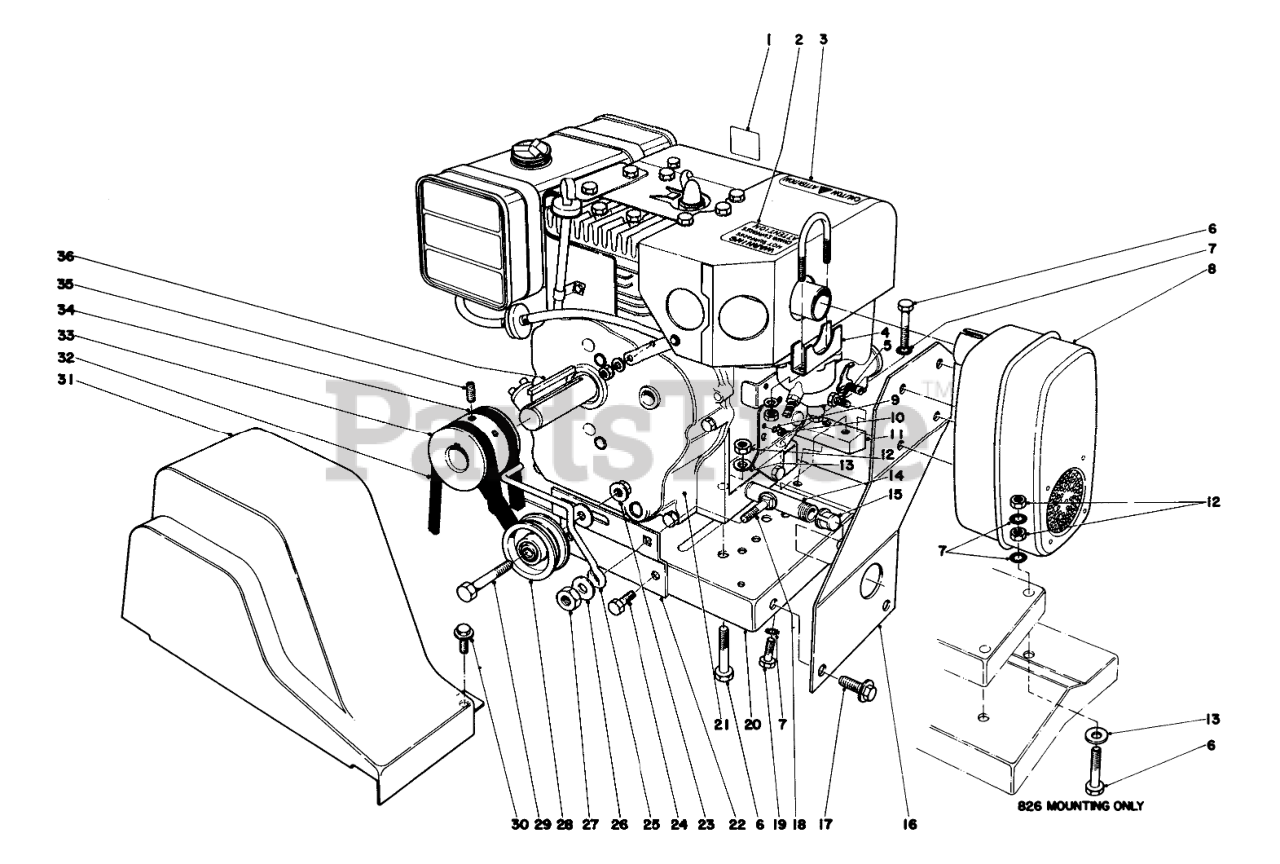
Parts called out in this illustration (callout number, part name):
1	CHOKE DECAL
2	Decal Hot Surface Warning
3	CAUTION DECAL
4	MUFFLER CLAMP
5	1/4-20 X 1/2 SEMS MS
6	SCREW-HH
7	WASHER-LOCK, INTERNAL
8	Muffler
9	WASHER-LOCK/INT
10	NUT-LOCK
11	Block Engine Mounting
12	NUT-LOCK, NI
13	WASHER-PLAIN
14	NIPPLE-PIPE
15	CAP-PIPE
16	Muffler Mounting Bracket
17	SCREW-HHF
18	SCREW-CARR
19	SCREW-HH
20	Base-Engine
21	Engine (Model 38070)
22	Belt Idler Bracket
23	NUT-HHF, WHIZ
24	SCREW-HHFTF
25	BELT GUIDE
26	WASHER-FLAT
27	NUT-HEX
28	PULLEY B
29	SCREW-HH
30	SCREW-HWH
31	BELT GUARD
32	V-BELT
33	ENGINE PULLEY
34	V-BELT
35	Screw-Set
